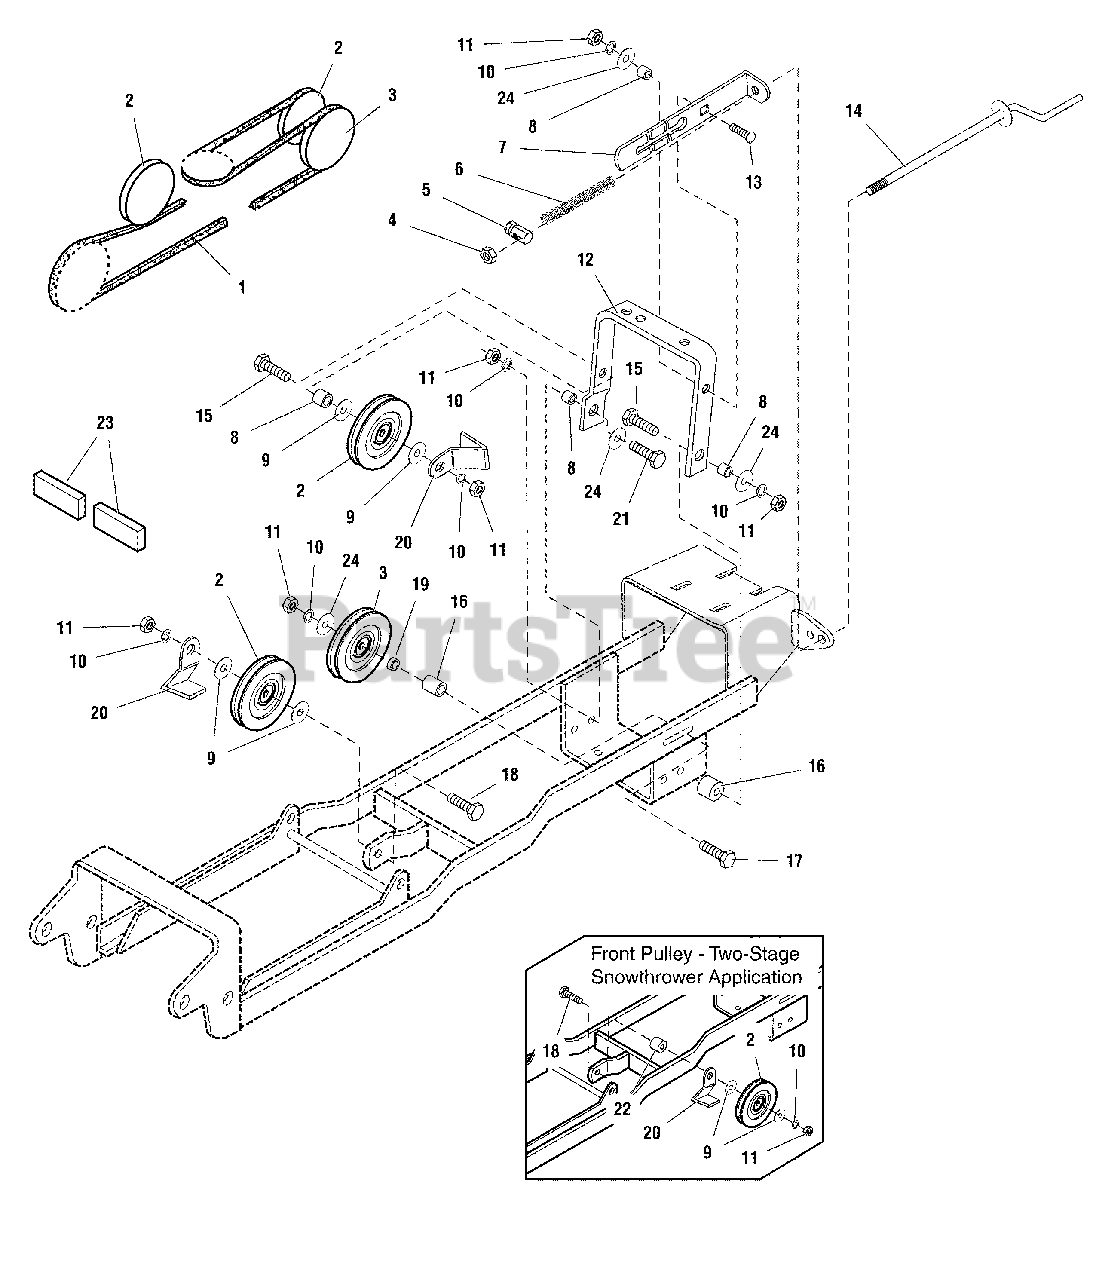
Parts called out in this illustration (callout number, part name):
1	V-BELT, Single-Stage Blower
1	V-BELT, Two-Stage Blower
3	PULLEY ASSEMBLY
4	NUT, Hex Lock, 3/8-16
7	GUIDE ASSEMBLY, Spring
9	WASHER, 3/8 x 1 x 1/8
10	LOCKWASHER, 3/8
11	NUT, Hex, 3/8-16
12	PIVOT BRACKET
13	CARRIAGE BOLT, 3/8-16 x 1-1/4
14	ROD ASSEMBLY
15	CAPSCREW, Hex Head, 3/8-16 x 2
17	CAPSCREW, Hex Head, Whizlock, 3/8-16 x 2-3/4
18	CAPSCREW, Hex Head, 3/8-16 x 2-1/4
20	BELT GUIDE
21	CAPSCREW, Hex Head, 3/8-16 x 1-1/4
22	SPACER, 3/8 x 1 x 1/2
24	WASHER, Plain 3/8
